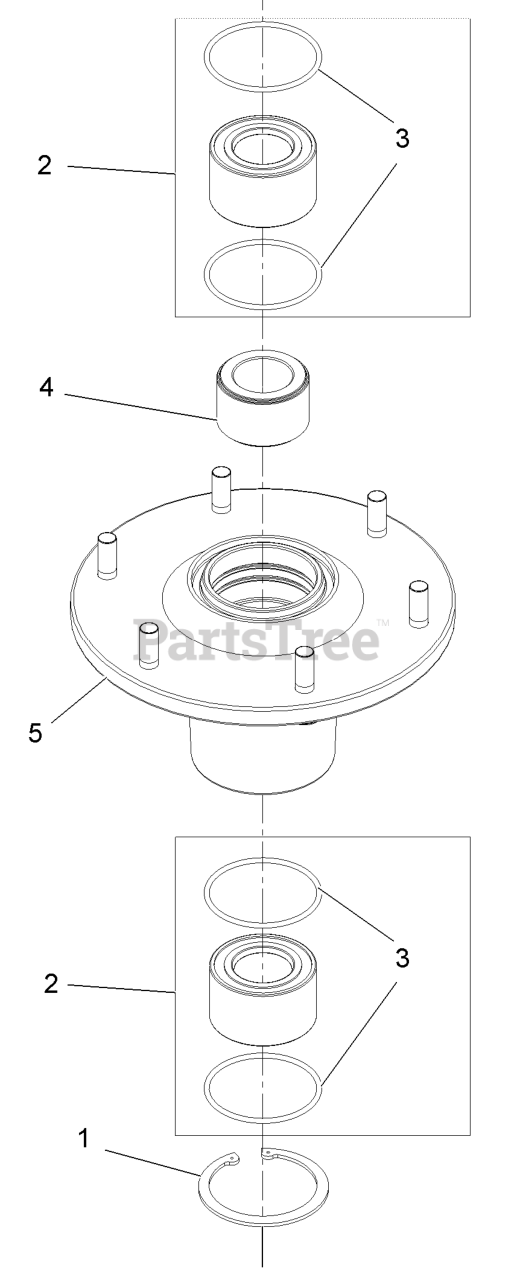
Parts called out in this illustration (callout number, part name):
1	RING-RETAINING
2	ASM, BEARING W/ORINGS
4	SPACER,BEARING
5	ASM,HOUSING W/STUDS
